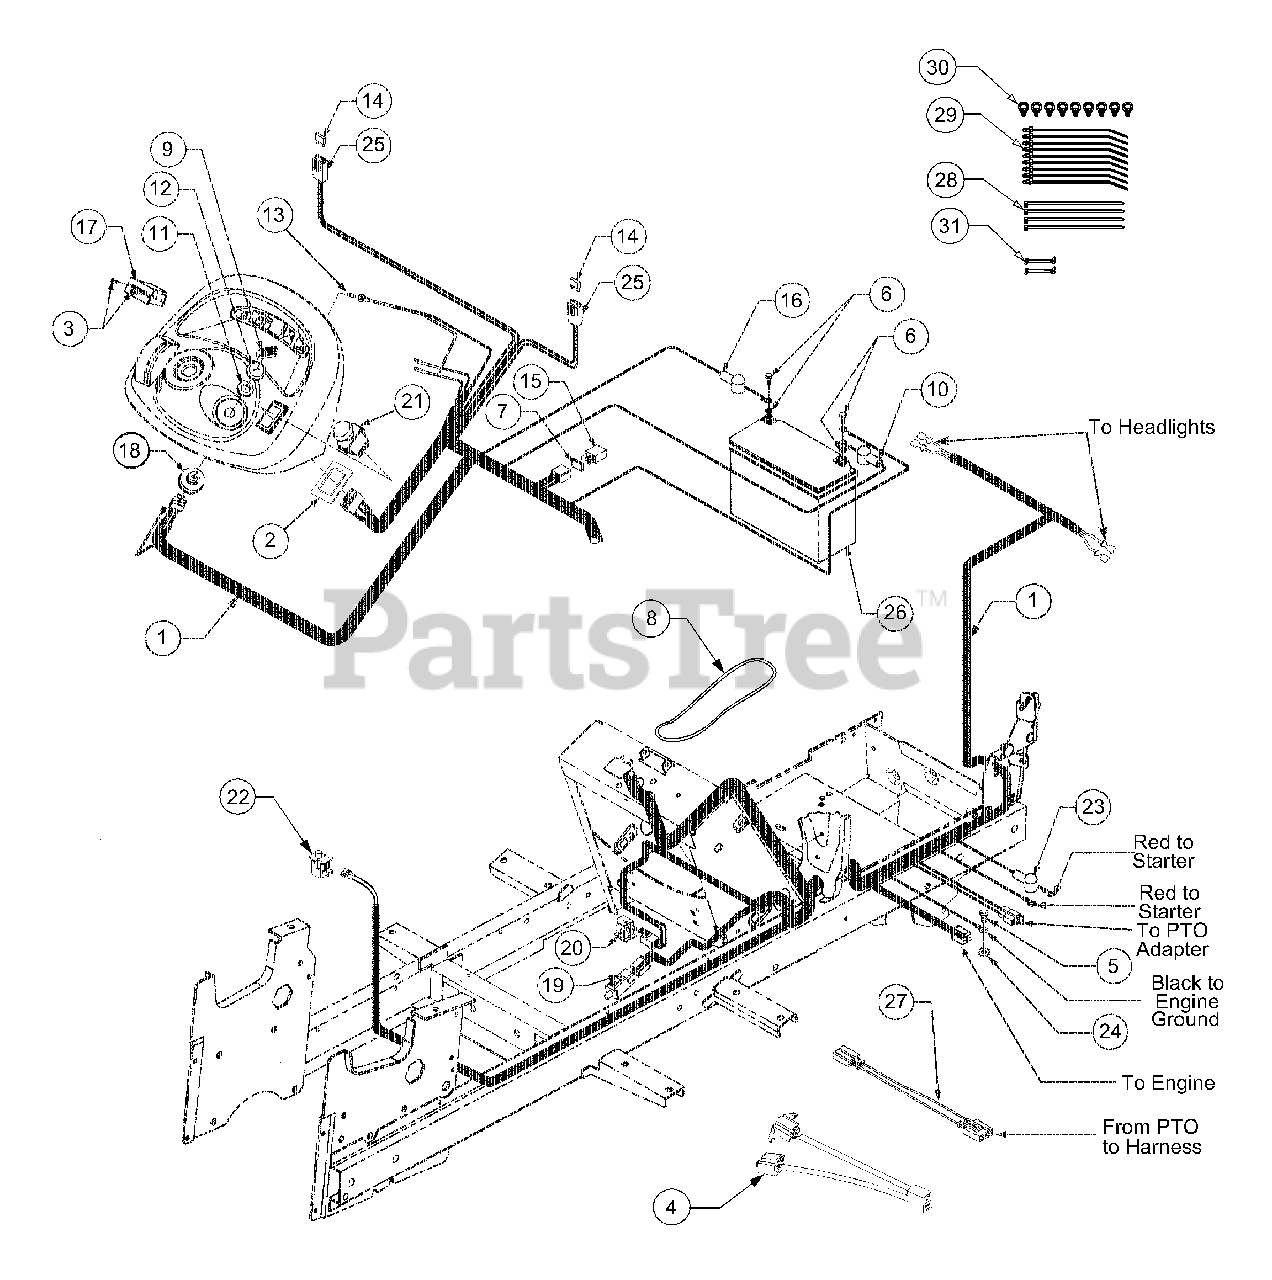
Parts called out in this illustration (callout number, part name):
1	Wire Harness, Main
2	Bracket, PTO Switch Retainer
3	Screw, Truss Hd Tapp, #6 x .62
4	Wire Harness, S.A.M.
5	Screw, Hex Cap, 5.16-24 x .625 GR5
6	Battery Cable Hardware
7	Gasket, Silicone
8	Strap, Battery Retainer
9	Key, Ignition (Set of 2)
10	Cover, Terminal Black
11	Nut, Ignition Switch
12	Cap, Ignition Switch
13	Bulb, Indicator
14	Fuse, 25 Amp
15	Relay
16	Cover, Terminal Red
17	Hour Meter
18	Switch, Ignition
19	Switch, Interlock (Brake)
20	Switch, Snap Mount
21	Switch, PTO
22	Switch, Snap Mount Seat
23	Cover, Terminal Red
24	Washer, External Lock, 5/16
25	Holder, Fuse w/Mounting Clip
27	Adapter, PTO Harness
28	Tie, Self-Clinch Cable
30	Tie, Pushmount
31	Clip, Cable
32	Clip, Wire
